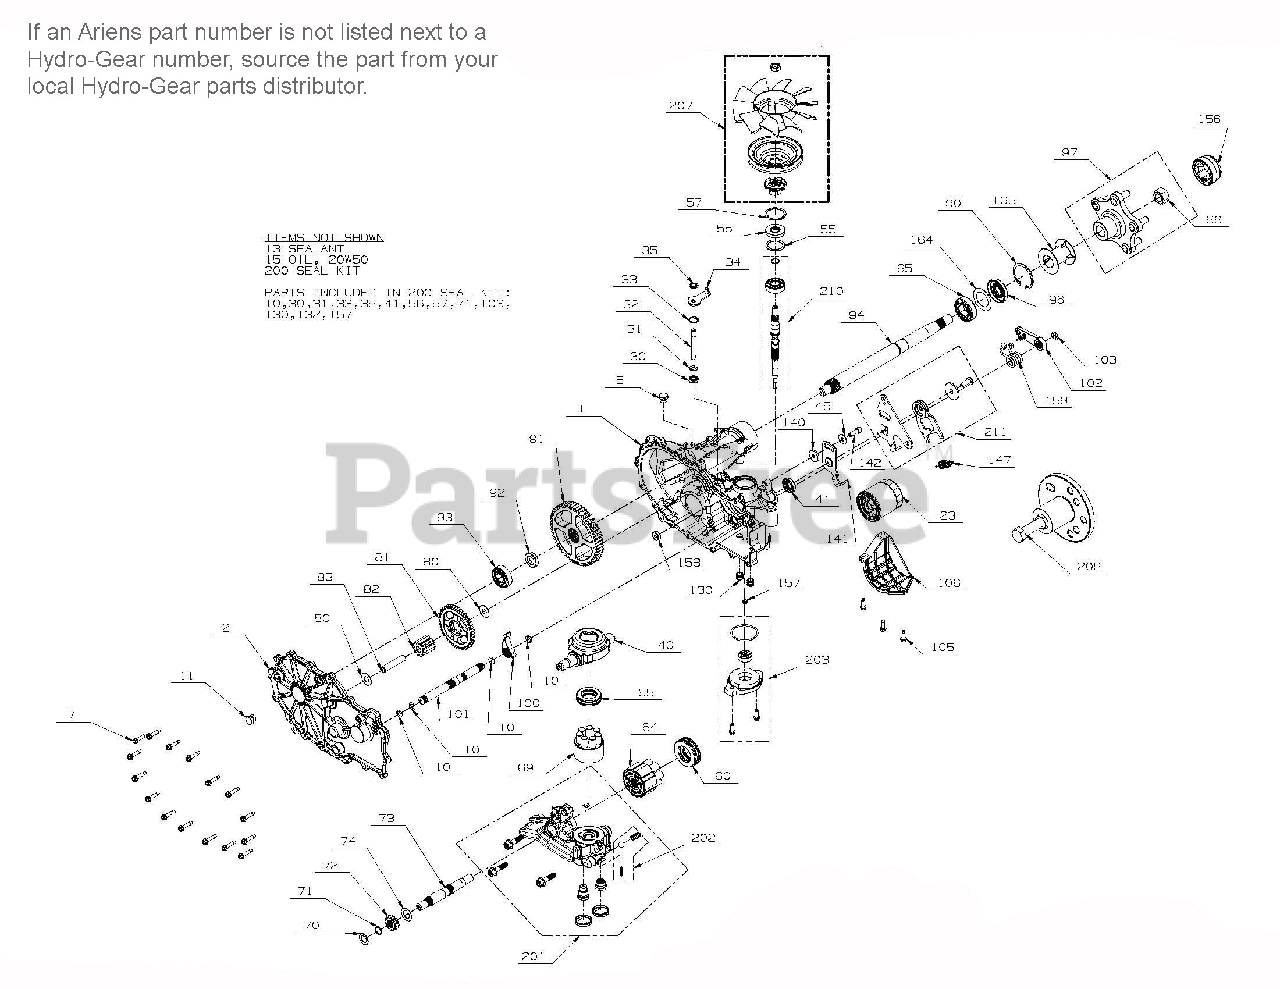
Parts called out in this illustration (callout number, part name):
7	SCREW, HEX WASHER
13	TUBE, SEALANT
15	OIL, 20W50
23	FILTER, SPIN-ON 2.6 X 3.0
30	SEAL, LIP .375 X .75 X .25
31	RING, RETAINING EXTERNAL .375
33	RING, RETAINING .750, INTERNAL
34	ARM, BYPASS
35	RING, RETAINING .375 EXTERNAL
40	SWASHPLATE, TRUNNION
41	SEAL, LIP 18 X 32 X 7
45	WASHER FLAT.34 X .88 X .06
55	WASHER, FLAT 1.23 X 1.57 X .04
56	SEAL, LIP 17 x 40 x 7
57	RING RETAINING INTERNAL
60	BEARING, THRUST 35 x 62 x 18
64	KIT, 16cc CYLINDER BLOCK ASSEMBLY
65	BEARING, THRUST PLASTIC CAGE
69	KIT, BLOCK 12cc
70	WASHER, .63 X 1.00 X .05 FLAT
71	RETAINING RING, MOTOR SHAFT
74	WASHER, .71 X 1.16 X .04 FLAT
80	WASHER, .51 X 1.00 X .03 FLAT
83	PIN, JACKSHAFT
90	RING, RETAINING 2.25 INTERNAL
95	BEARING, BALL 6205R-1 25.4 x 52 x 15
96	SEAL, LIP, TC4, 1.0 X 2.06 X .38
97	KIT, HUB - 5 BOLT
99	NUT, HEX LOCK 3/4-16
102	KIT, LEFT HAND BRAKE ARM
105	SCREW, HEX WASHER 1/4-20 X .75
106	GUARD, FILTER, LH
140	SPACER 0.320 ID X 1.005 OD X 0.1495 THK
141	ARM, RETURN LEFT
142	SHCS 5/16-24 x 7/8 (W/PATCH)
147	SPRING, EXTENSION
158	MAGNET, RING
200	KIT, SEAL, ZT-3400
203	KIT, CHARGE PUMP
211	KIT, RTN COW
